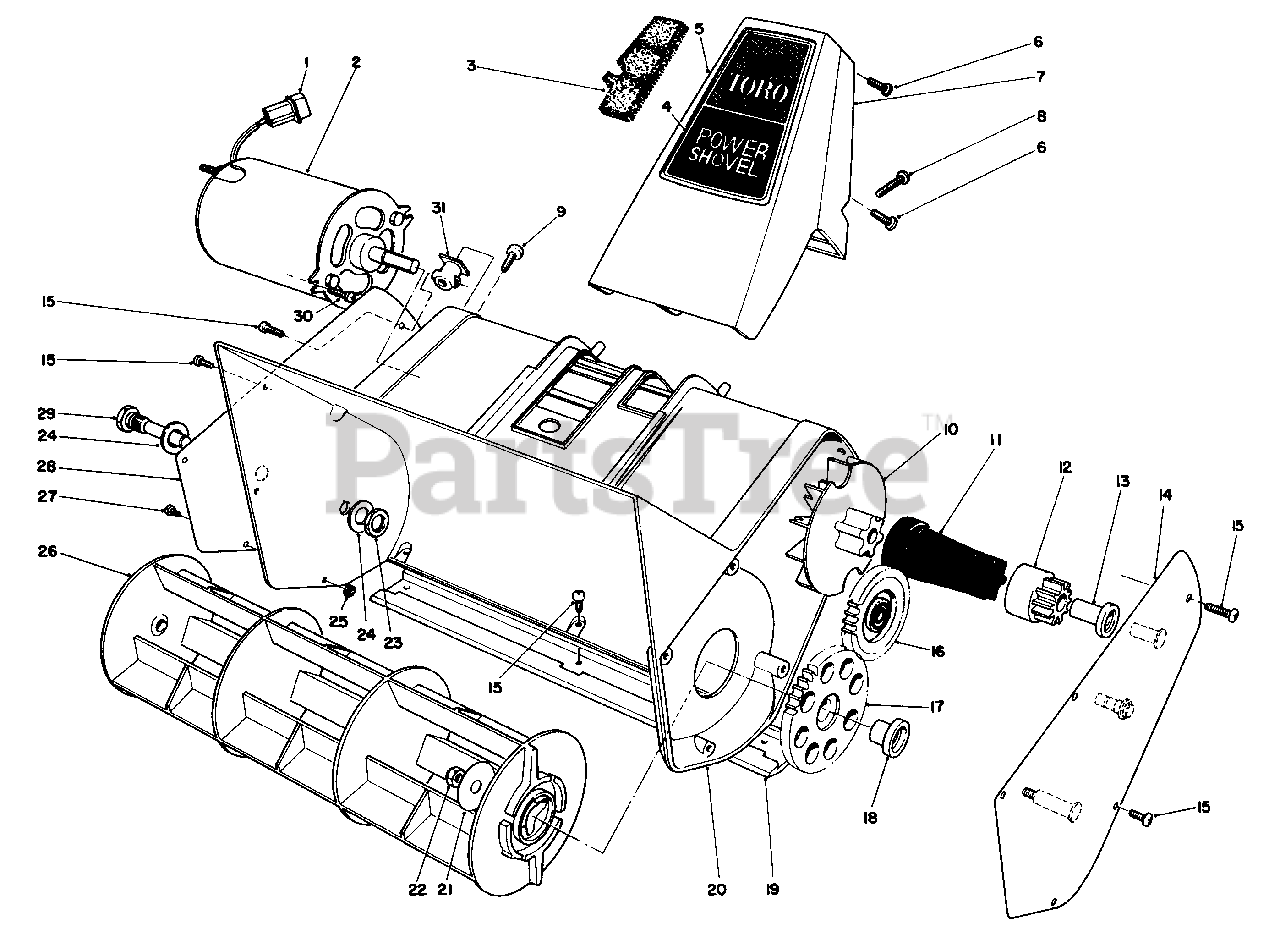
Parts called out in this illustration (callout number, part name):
1	Housing-Pin
2	Motor (Incl. Ref. #1)
3	Filter-Foam
4	Decal-Handle Support
5	Handle Support-Front
6	Screw-Pan Head
7	Handle Support-Back
8	Screw-Pan Head
9	Screw-Phillips Head
11	Coupling-Drive
12	Drive Gear (Incl. Ref. #13)
13	Bushing-Drive Gear
14	Gear-Carrier
15	Screw-Pan Head
16	Idler Gear Assembly
17	Rotor Gear Assembly (Incl. Ref. #18)
18	Bushing-Rotor
20	Housing
21	Washer-Rotor
22	Nut-Lock
23	Nut-Lock
24	Flat Washer
25	Nut-Lock, Thin
27	Screw-Pan Head
28	Cover-Right Side
29	Pin-Rotor
30	Screw-Pan Head
31	Block-Mounting
